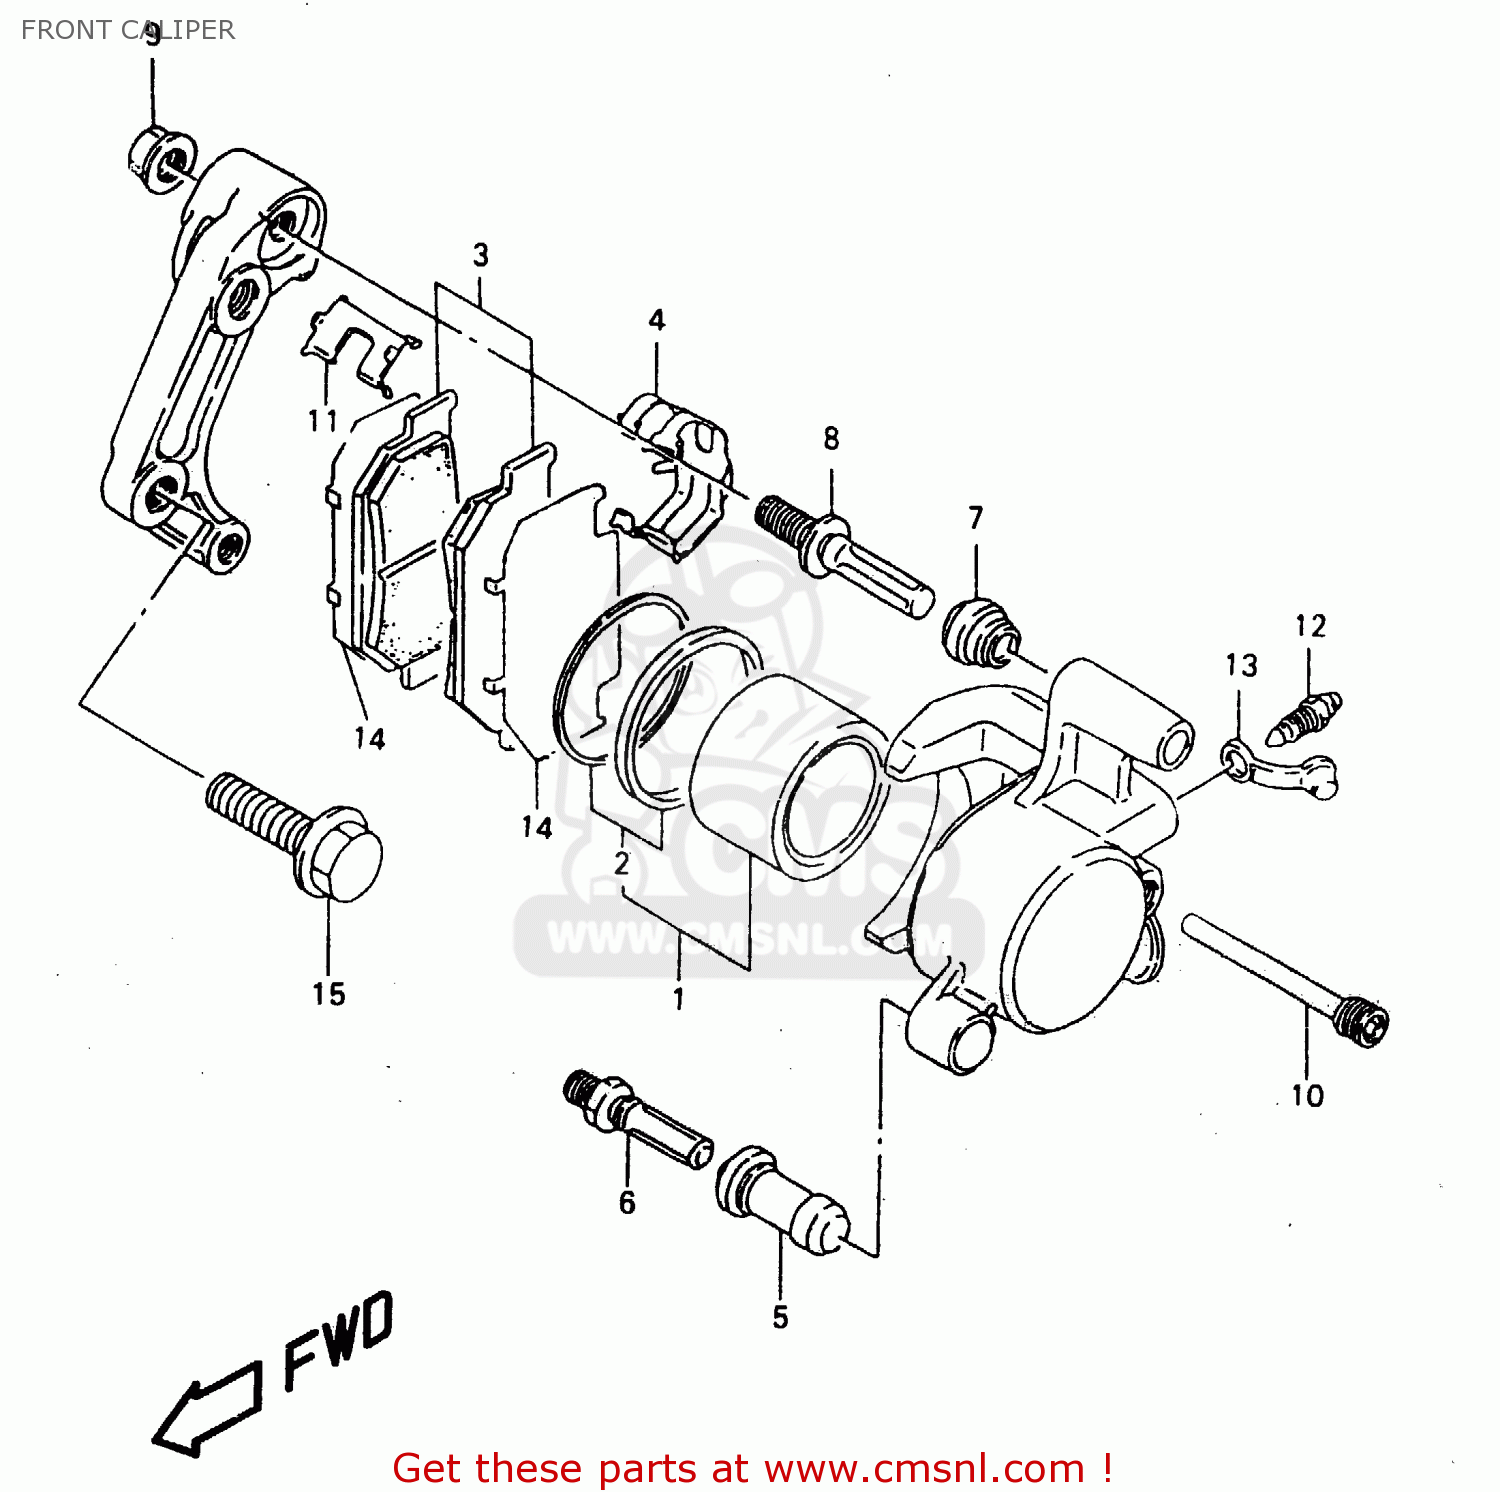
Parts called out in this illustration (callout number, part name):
1	PISTON SET
2	SEAL SET,PISTON
3	PAD SET (NAS)
4	SPRING
5	BOOT
6	PIN,BOLT
7	BOOT
8	PIN,SLIDE
9	NUT,SLIDE PIN
10	PIN,HANGER
11	RETAINER
12	BLEEDER
13	CAP,BLEEDER
14	SHIM
15	BOLT
